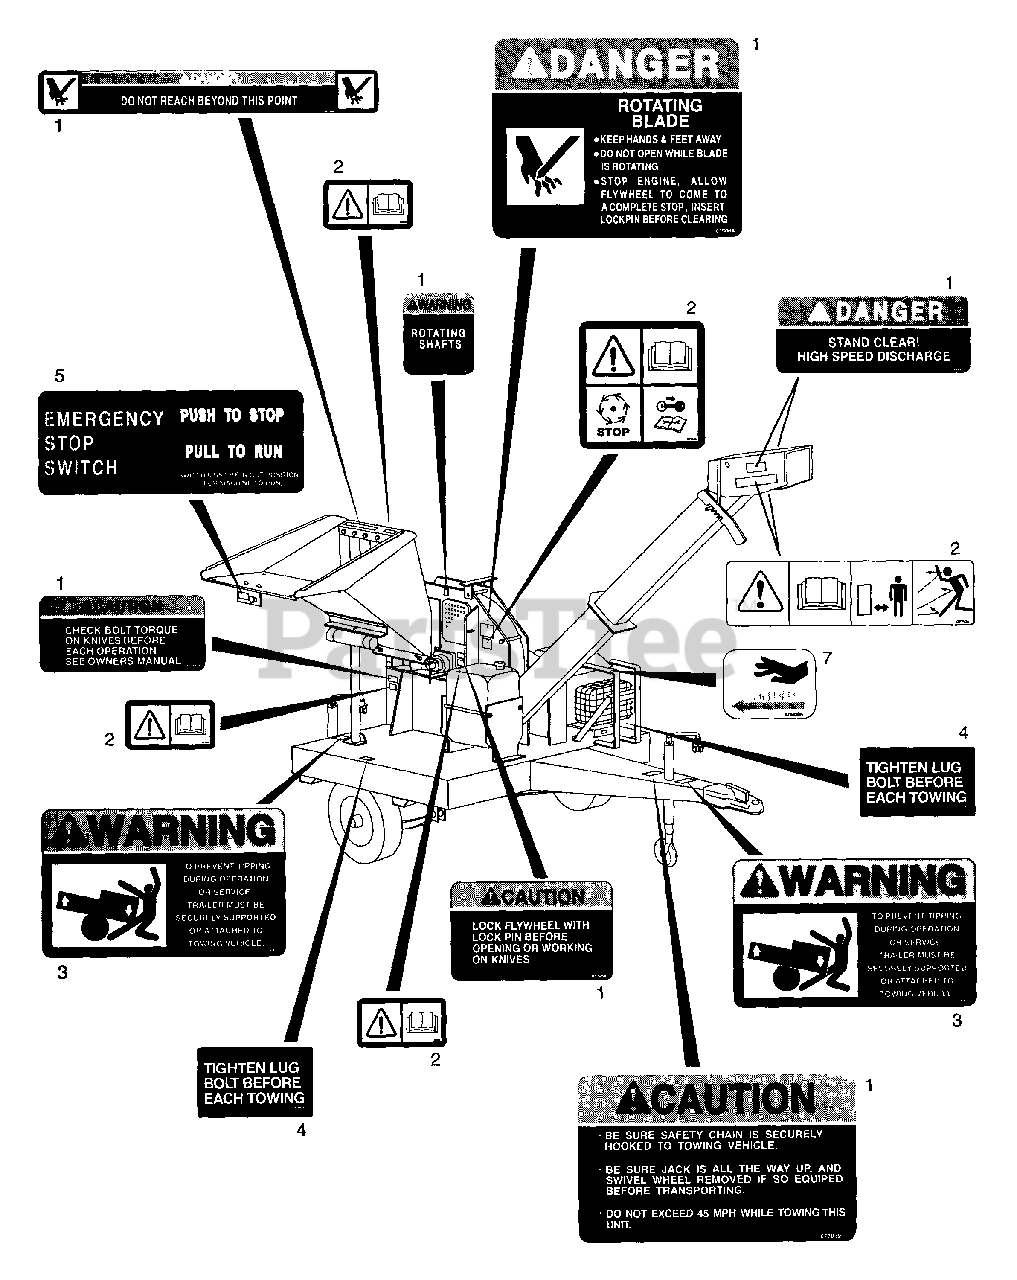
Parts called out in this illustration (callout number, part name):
1	Decal Set, Large Chippers
2	Decal Set, Chipper CE
3	Decal, Warning Tipping
4	Decal Set, Chipper Black & White
5	Decal Set, 210
7	Decal, Hot Surface
